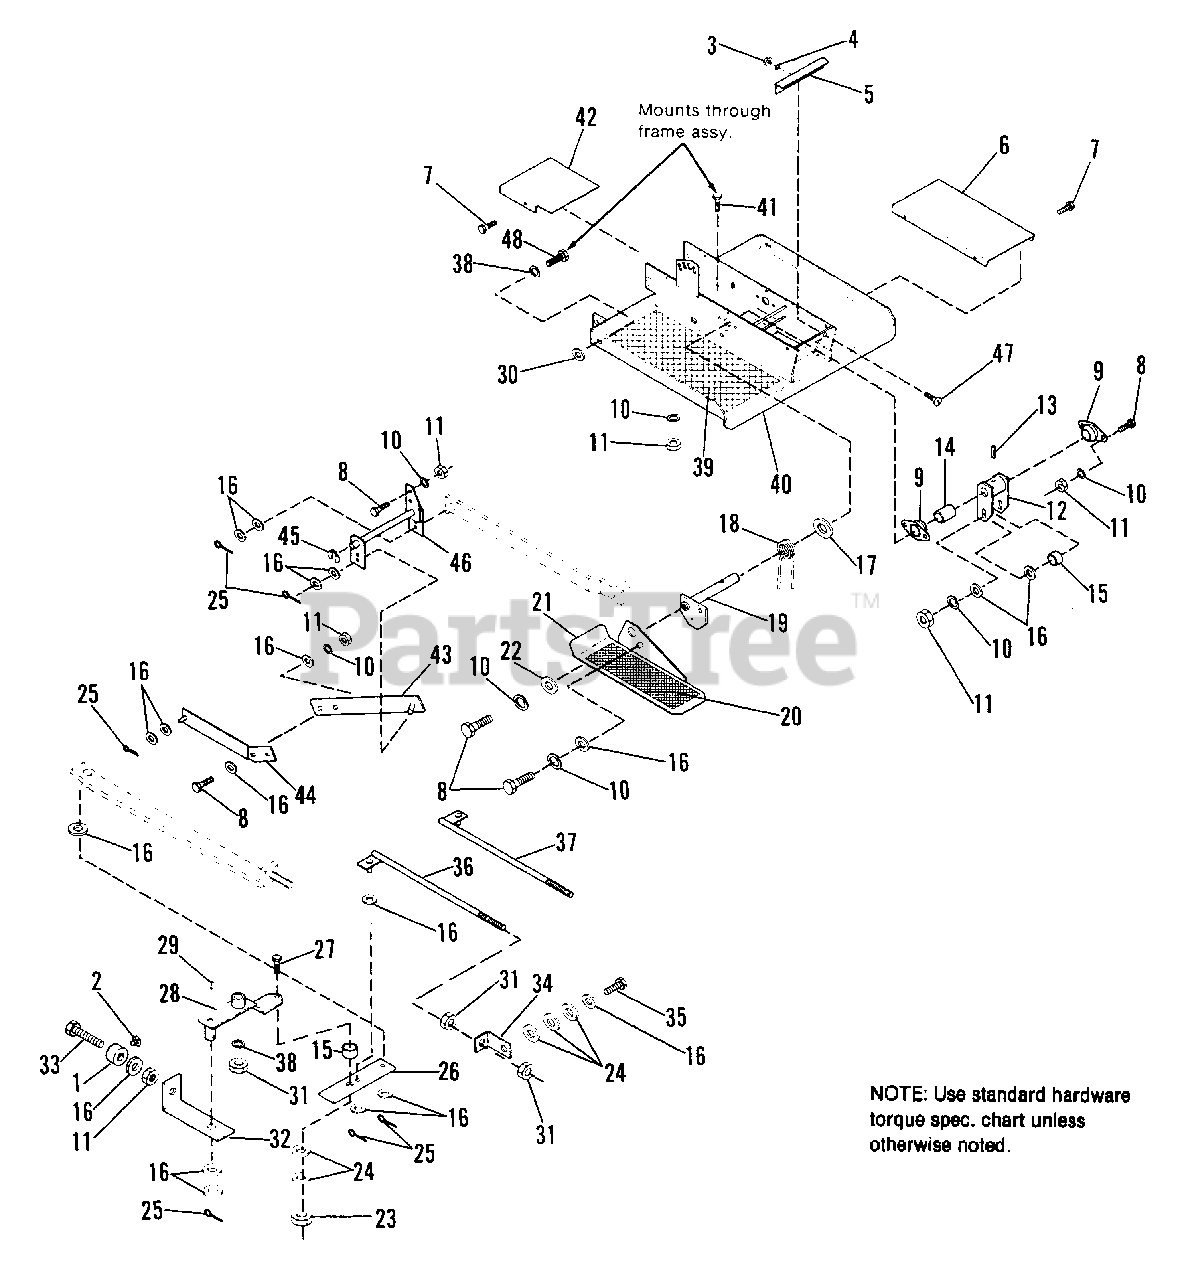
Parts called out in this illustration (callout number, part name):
1	COLLAR, Set
2	SETSCREW, Sq. Hd., 1/4-20 x 3/8
3	NUT, Hex, #10-24
4	LOCKWASHER, #10
5	CLAMP, Light
6	COVER, Front
7	SCREW, Taptite, 1/4-20 x 5/8
8	CAPSCREW, Hex, 5/16-18 x 3/4
9	BEARING, Flanged
10	LOCKWASHER, Spring, 5/16
11	NUT, Hex, 5/16-18
12	ARM ASSY.
16	WASHER, Plain
17	WASHER, Plain
18	SPRING, Torsion
19	SPEED CONTROL SHAFT ASSY.
20	PAD, Non-Skid
21	PEDAL, Control
22	WASHER, Plain
23	LOCKNUT, Hex, Flanged, 5/16-18
24	WASHER, Plain
26	BAR
27	CAPSCREW, Hex, 5/16-18 x 1
28	CONTROL ARM ASSY.
29	KEY, Hi-Pro, 1/8 x 1/2
30	WASHER, Plain
31	NUT, Hex, 3/8-16
32	STOP ASSY., Forward Travel
33	CAPSCREW, Hex 5/16-18 x 2-3/4
34	LINK, Adjusting
35	CAPSCREW, Hex, 5/16-18 x 1-1/4
36	SPEED CONTROL LINK ASSY., R.H.
37	SPEED CONTROL LINK ASSY., L.H.
38	LOCKWASHER, 3/8
39	PAD, Non-Skid
40	FOOTREST ASSY.
41	CAPSCREW, Hex 5/16-18 x 1-3/4
42	COVER, Rear
43	LINK ASSY., Clutch. Rear
44	LINK ASSY., Adjusting
45	KLIPRING, 1/2"
46	SHAFT ASSY.
47	SCREW, Pan Hd., #10-24 x 1
48	CAPSCREW, Hex, 3/8-16 x 1
